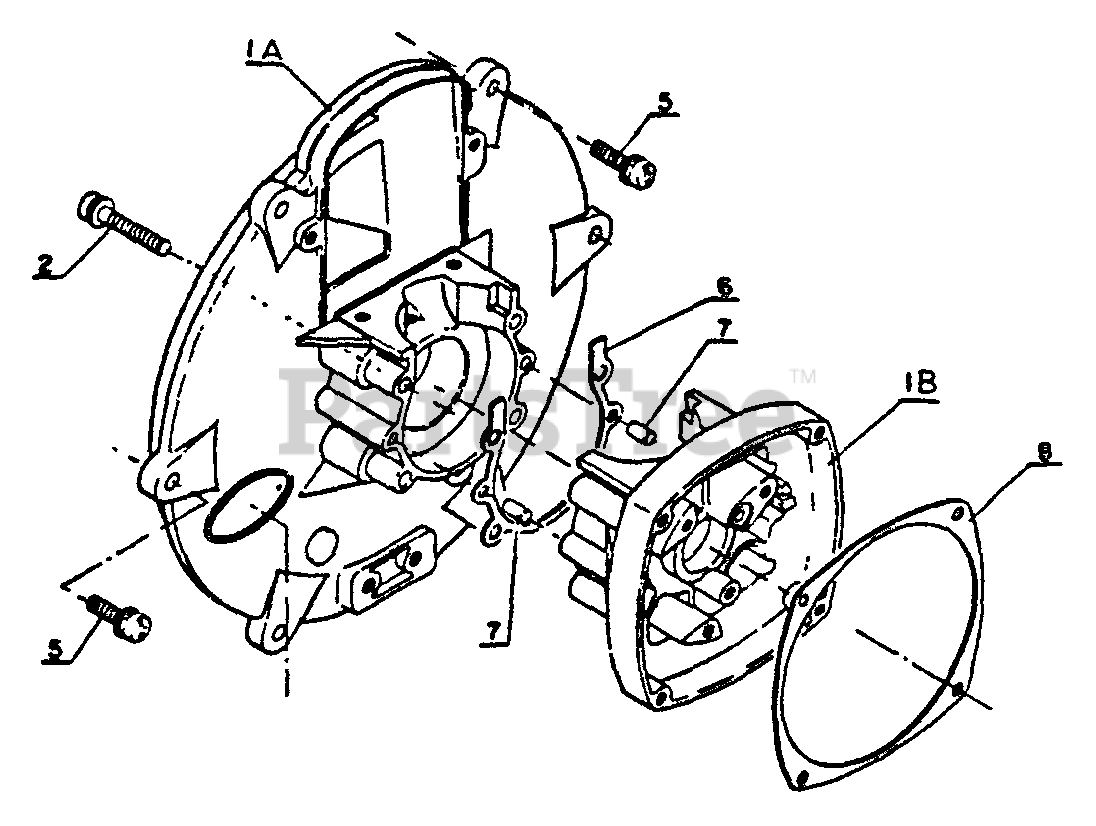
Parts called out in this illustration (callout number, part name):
1	CRANKCASE KIT
2	SCREW 5×28
5	SCREW 5×18
6	GASKET, CRANKCASE
7	PIN, LOCATING 4
8	GASKET, STARTER
